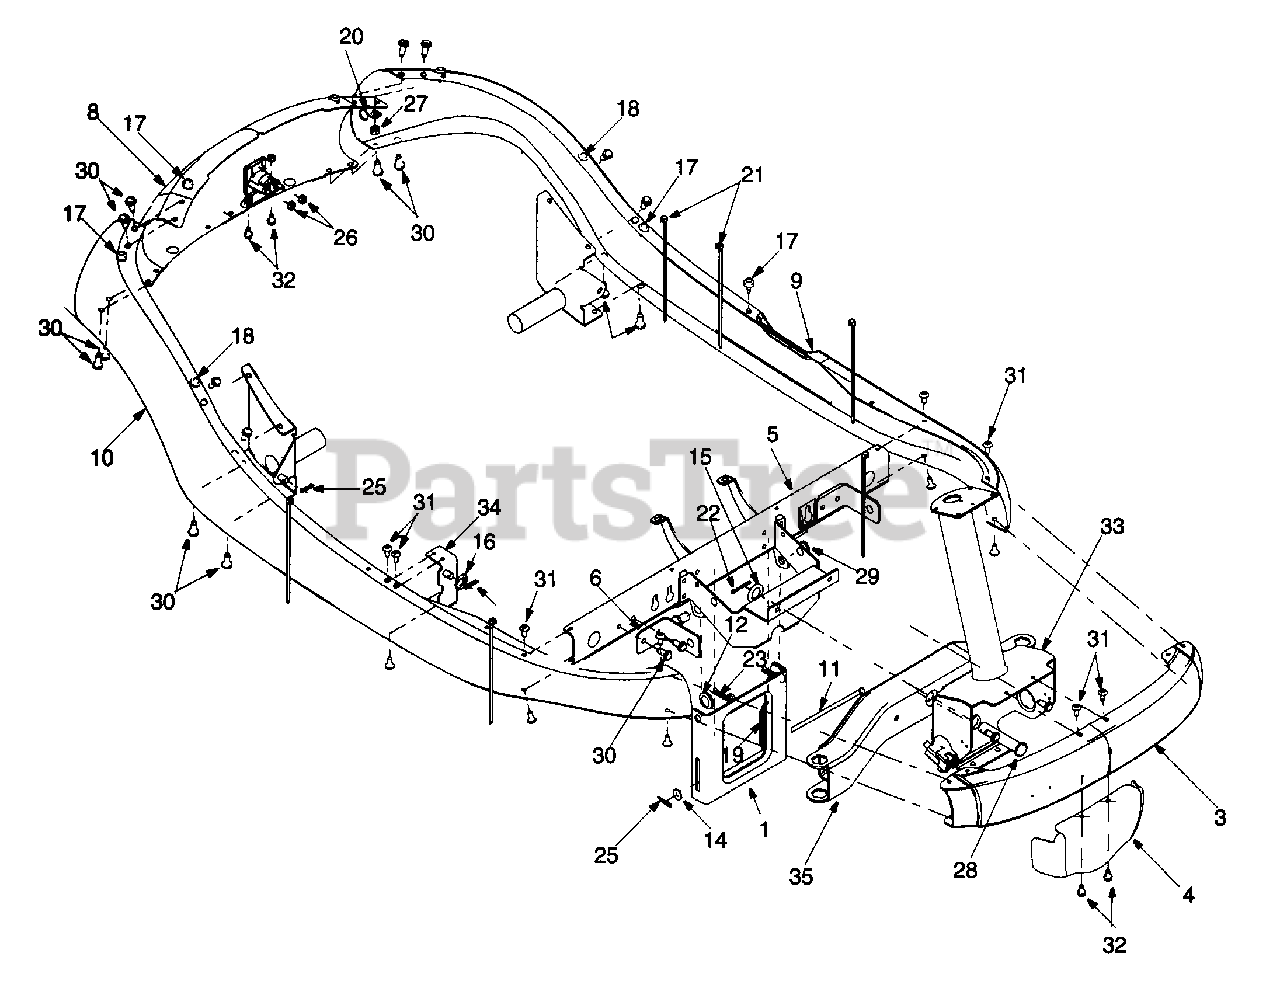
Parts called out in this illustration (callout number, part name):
12	Flat Washer .531 x 1.062 x .134
14	Flat Washer 5/16
15	Flat Washer .64 I.D. x 1.24 x .06
16	Flat Washer 3/8 x 1.00 x .030
17	Bumper
18	Rubber Bumper
19	Extension Spring
20	Clamp: 9/16 dia.
21	Cable Tie
22	Hairpin Clip
23	Hairpin Clip
25	Hairpin Clip
26	Hex Nut
27	Hex Nut 1/4-20
28	Clevis Pin
29	Lift Bracket Pin
30	TT Screw 5/16-18 x .75
31	Torx Mach. AB Scr. 1/4-14 x 0.625"
32	Hex TT Screw 1/4-20
